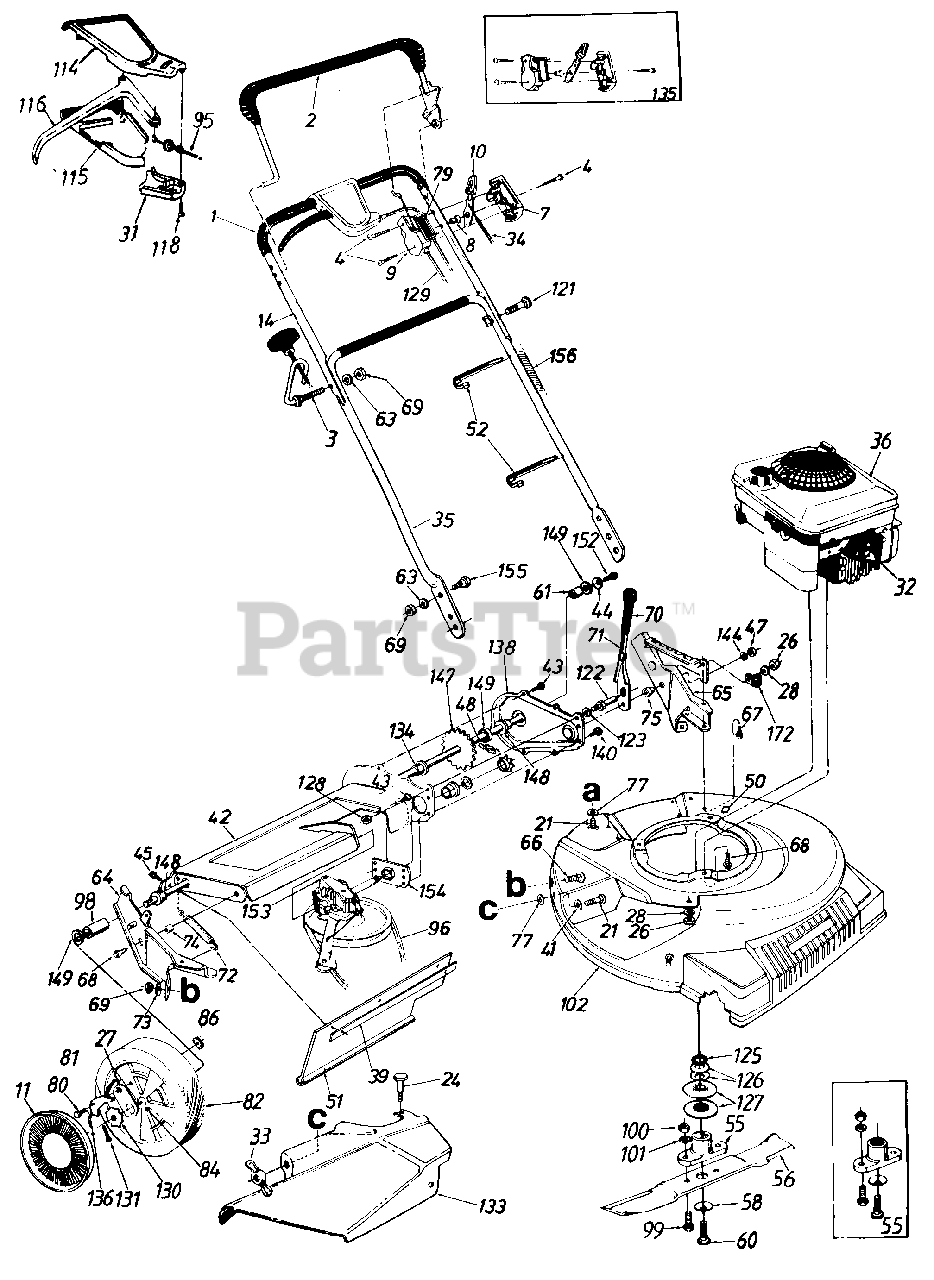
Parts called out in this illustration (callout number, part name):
1	Grip
2	Control Handle Ass'y. L.H.
3	Rope Guide Bolt
4	Truss Mach. Scr. #12 x 1.50" Lg.
7	Control Panel Half
8	Control Disc Pin
9	Clutch Panel Half
10	Throttle Control Lever
11	Hub Cap
14	Upper Handle
21	Carriage Bolt 1/4-20 x .62"
24	Shoulder Bolt Special
26	Hex Nut 1/4-20 Thd.
27	Pawl Plate
28	L-Wash. 1/4" I.D.
31	S.P. Control Cover
32	Spark Plug Insulator
33	Wing Nut
34	Throttle Control Wire 61"
35	Lower Handle
36	Engine
39	Retaining Strip
41	Fl-Wash. .344" I.D. x .62"
44	Bell-Wash. 1/4" I.D.
45	Hex AB-Tap Scr. 1/4 x .62"
47	Hex Patch L-Nut 3/8-24 Thd.
48	#48 Chain .500" Pitch x 30 Links
51	Rear Flap 3.75" x 17.30" Lg.
52	Cable Tie
55	Blade Adapter Kit
56	21" Blade
58	Bell-Wash. .46" I.D. x 1.13"
60	Hex Bolt 7/16-20 x 1.5"
61	Spacer .513" I.D.
63	L-Wash. 5/16" I.D.
64	R.H. Handle Wheel Brkt. Ass'y.
65	L.H. Handle Wheel Brkt. Ass'y.
66	Carriage Bolt 5/16-18 x .62"
67	Hex B-Tap Scr. 5/16-18
68	Hex TT-Tap Scr. 3/8-16
69	Hex Nut 5/16-18 Thd.
71	Height Adj. Lever
72	Extension Spring 3.80" Lg.
73	Bell-Wash. 5/16" I.D.
74	Spacer .383" I.D.
75	Shld. Spacer .5" Dia.
77	Bolt Retainer 1/4 x .50" O.D.
79	Control Label
80	Shld. Scr. .342" Dia. x .268
81	Pawl
82	Wheel Ass'y. Comp. Rear
84	Sleeve Bearing 1/2" I.D.
86	Flat Nut 1/4-20 Thd.
95	S.P. Cable 50" Lg.
96	"V"-Belt
98	Sleeve .526" I.D.
99	Hex Bolt 3/8-24 x 1.0" Lg.
100	Hex Nut 3/8-24 Thd.
101	L-Wash. 3/8" I.D.
115	Self-Propelled Control Cover
116	Control Lever
118	Fl-"C"-Sunk Hd. Tap Scr. #10 x .75" Lg.
121	Curved Carr. Bolt 5/16-18 x 1.38" Lg.
122	Shld. Pin 1.43" Lg.
123	L-Wash. 3/8" I.D.
125	Crankshaft Spacer
126	Bell-Wash. 1.01" I.D.
127	Serrated Pulley Half
128	Hex Jam Nut 3/8-24 Thd.
129	Control Cable 46"
130	Ratchet Wheel 1.62" O.D.
131	Cotter Pin 1/8" Dia. x 1"
133	Side Chute Deflector Ass'y.
134	Hex Flange Bearing
135	Kit Control Housing Comp.
136	Spring Nylon
144	Fl-Wash. .385" I.D. x .87"
147	Rear Shaft Ass'y. 21.94" Lg.
148	Hex Flange Brg. .506" I.D.
149	Fl-Wash. .531" I.D. x .930"
152	Hex Bolt 1/4-20 x .62" Lg. (Grade 5)
153	Transmission Comp.
155	Truss Mach. Scr. 5/16-18 x .75" Lg.
156	Plastic Tubing
172	Clamp
